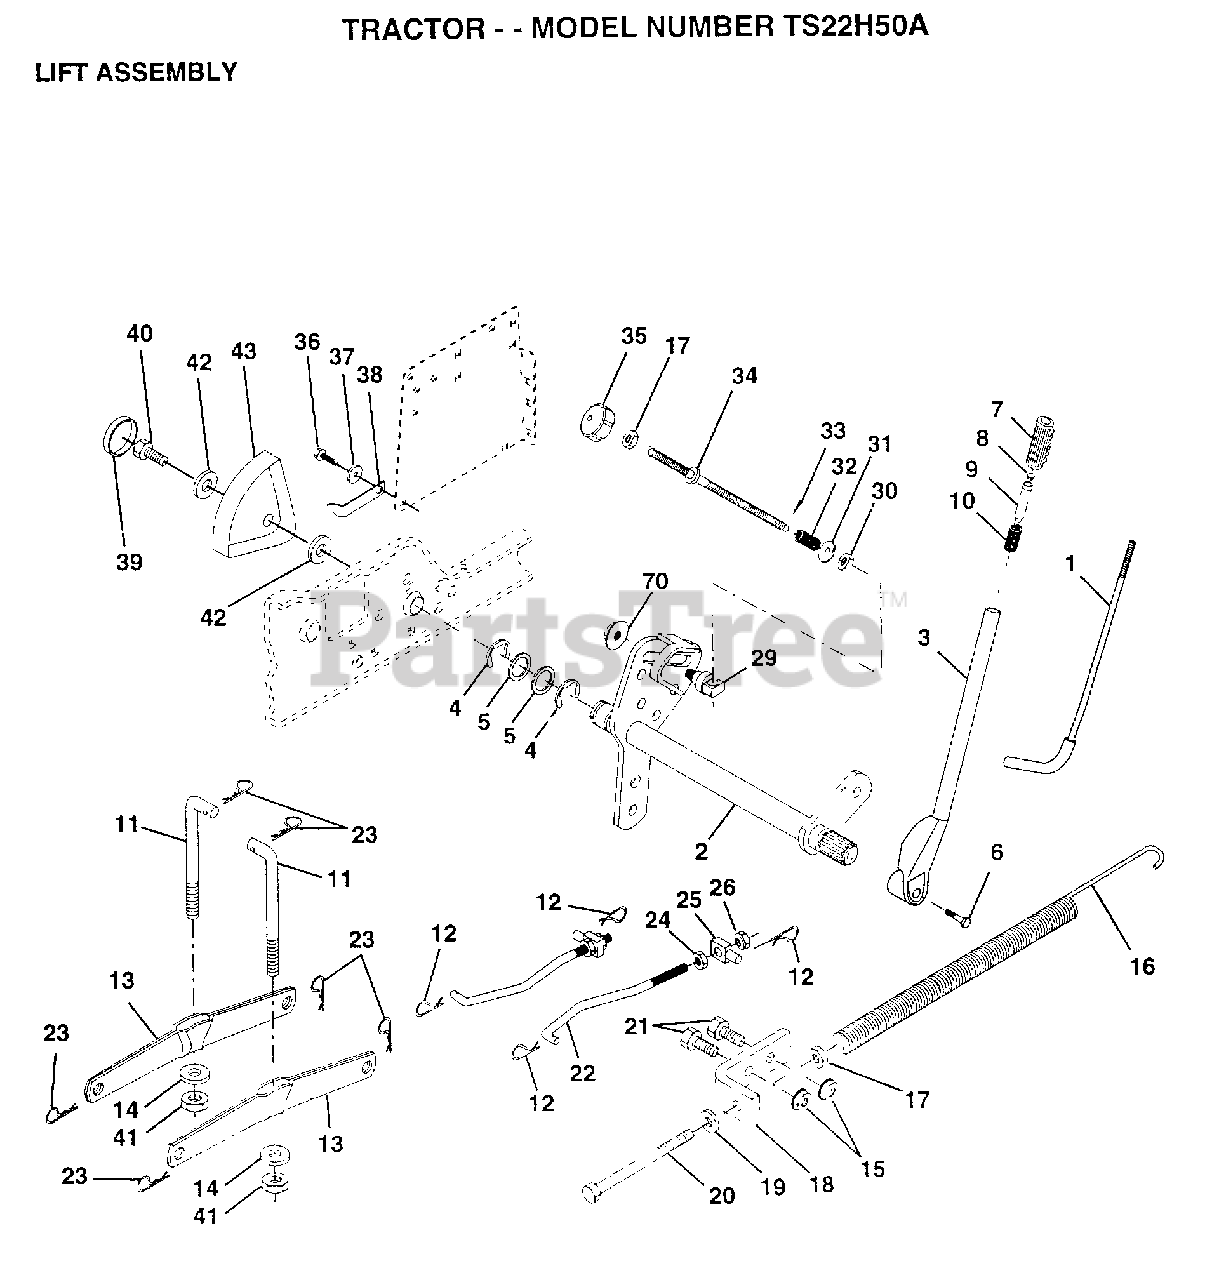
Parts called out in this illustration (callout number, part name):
1	LEVER ROD LT
2	SHAFT.LIFT.VGT.95
4	E-RING
5	WASHER
6	"BOLT,HEX"
7	GRIP HANDLE
8	BELT
10	SPRING T
11	LINK.LIFT.MWR.VGT
12	RETAINER.SPRING
13	ARM SUSP REAR
14	BEARING PVT LH
16	SPRING, ASM.
17	NUT
18	BRACKET SPRING AS
19	WASHER
20	BOLT-ADJ SPRING T
21	BOLT
22	LINK.FRONT
24	NUT
25	TRUNION
26	NUT.LK.W/WSH.1/2.
29	TRUNNION
30	NUT T
31	WASHER
32	SPRING.COMP.INF.H
34	ROD.ADJ.LIFT
35	KNOB INF 3/8-16
36	SCREW
37	WASHER T
38	POINTER HGT IND
39	"PLUG,HOLE"
40	SCREW
41	NUT.CROWNLOCK.3/8
42	WASHER
43	HEIGHT INDICATOR
70	NUT.HXFLG.LOCK.
